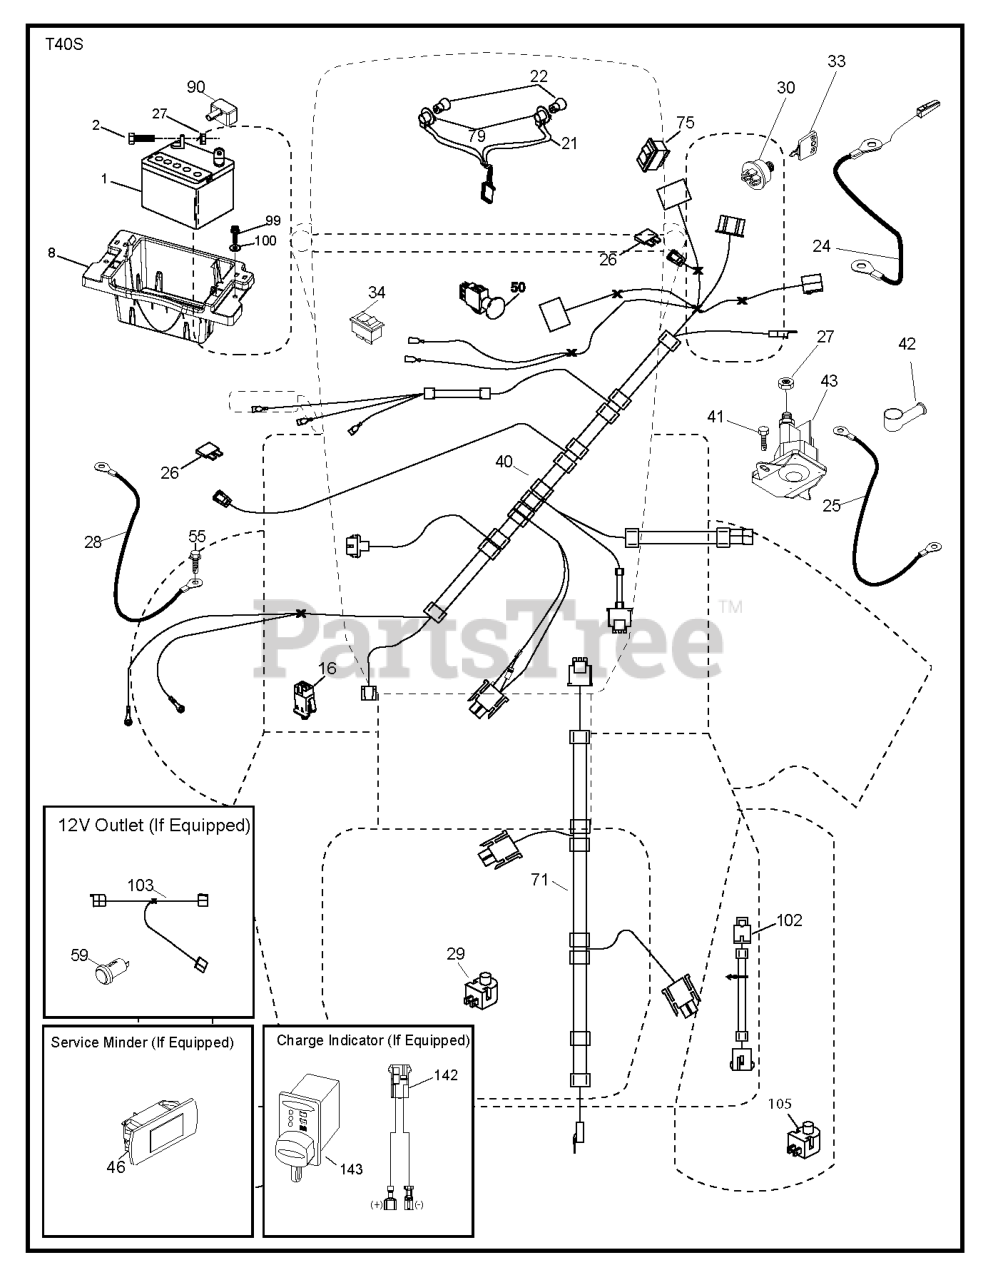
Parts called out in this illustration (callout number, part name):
1	REPL BY 532 12 38-99
2	BOLT.HEX.1/4.X.3/4.DICHROMATE
8	TRAY.BATTERY BOX.FRONT
16	SWITCH INTERLOOK PUSH-IN
21	HARNESS.LIGHT W/4152J BULBS
22	LIGHTBULB
24	CABLE.FRBATT.W/WIRE.8GA.8
25	CABLE.STARTER.8GA.17.5
26	FUSE 20AMP
27	NUT
28	CABLE.GROUND.21"BLK.8GA.90T
29	SWITCH.SEAT.DP W/RAMPS
30	SWITCH.IGN.DELTA.W.LGH.ROS
33	KEY.CHAIN.BLISTER.PACK.GEN.INT
34	SWITCH LT
40	HARNESS DASH DIFF LOCK HARNESS
41	SCREW
42	TERMINAL COVER
43	SOLENOID.STARTER.BRASS.PLUNGER
46	GUAGE.SRVCMNDR.HRMTR.
50	SWITCH.PTO.8TERMINAL.STD.BLK
55	SCREW 5/16"
71	HARNESS.IGN.CHASSIS.TEX.DCKLOC
75	SWITCH.ON/OFF.(DIFF.LOCK)
79	BULB HOLDER ASM.
90	COVER.TERMINAL.BATTERY
99	SCREW HEXWSHR 1/4-20X3/4
100	WASHER
102	HARNESS PIGTAIL PCH TEX ROS
105	REVERSE SWITCH
